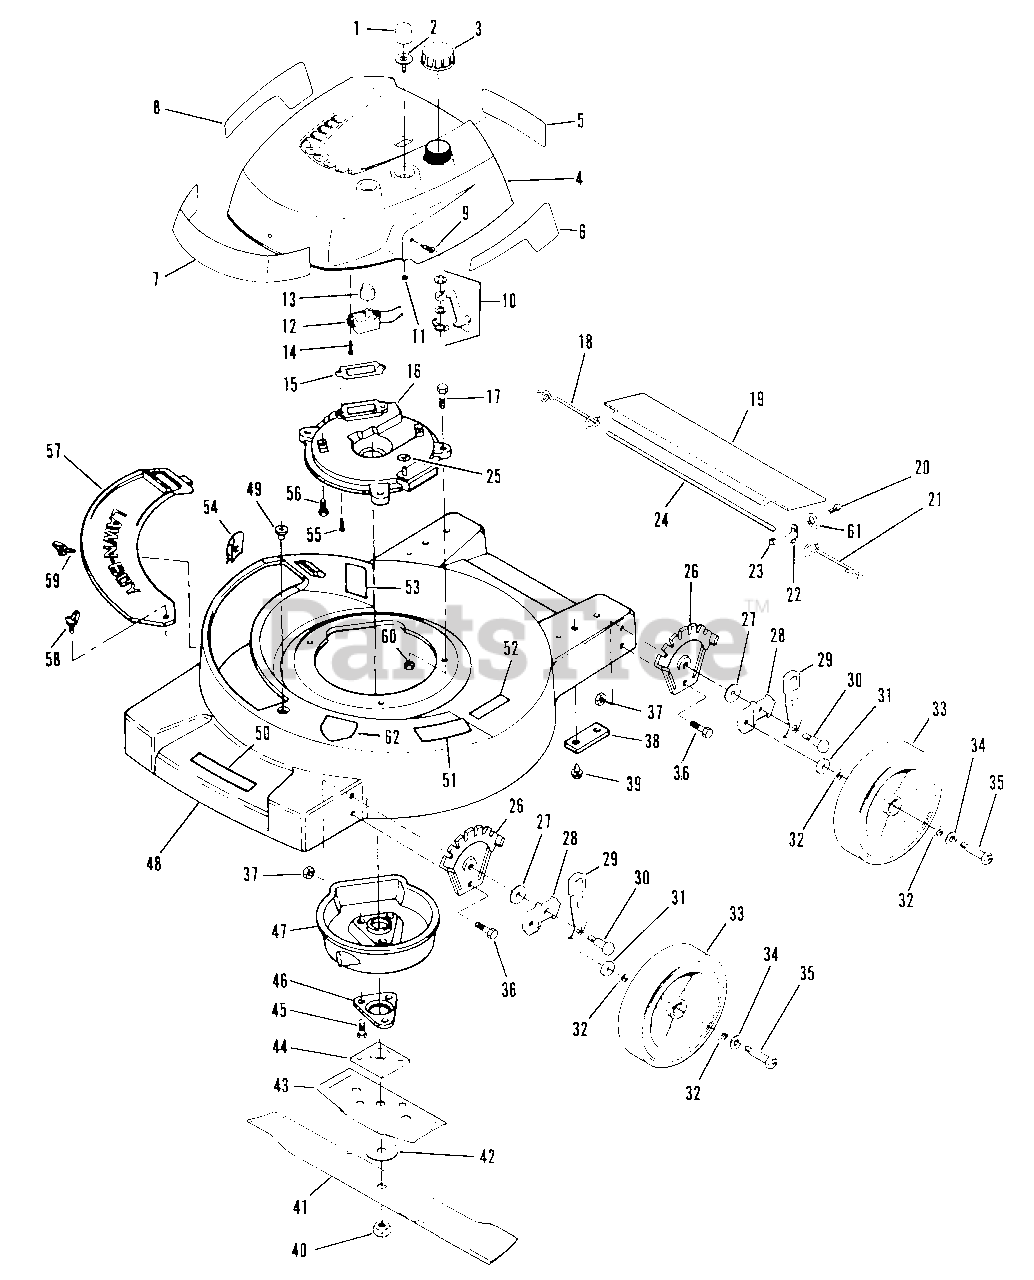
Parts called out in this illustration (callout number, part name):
1	Bulb-Primer
2	Base-Primer
3	Fuel Cap
4	Shroud-Engine
5	Decal-Instructions
6	Decal-L.H.
7	Decal-Lawn-Boy
8	Decal-R.H.
9	Screw-Shroud Mounting
10	Fuel Shut-Off Assembly
11	Nut
12	Switch-On-Off
13	Knob
14	Screw
15	Gasket-Exhaust
16	Plate-Muffler
17	Screw-Muffler Plate to Housing
18	Spring-R.H.
19	Shield-Trailing 21"
20	Screw
21	Spring-L.H.
22	Clamp
23	Nut
24	Rod-Trailing Shield 21"
25	Pushnut-Model Plate Mtg
26	Plate-Height Adjust
27	Washer
28	Bracket-Wheel Height Adjustment
29	Knob & Spring Assembly
30	Shoulder Bolt
31	Washer
32	Washer-Felt
33	Wheel
34	Washer
35	Bolt-Wheel
36	Screw-Plate Height Adjustment
37	Nut-Back-Up Plate & Adjustment Bracket
38	Spacer-Handle Bracket Screw
39	Screw-Handle Bracket to Housing
40	Nut-Blade
41	Blade-21"
42	Washer-Blade
43	Stiffener-Blade
44	Collar & Plate Assembly
45	Screw
46	Support-Crankshaft
47	Muffler Cover Assembly
48	Housing-21"
49	Grommet
50	Decal-Caution
51	Pad-Starting
52	Decal-Starting Pad
53	Decal-Discharge Area
54	Speed Nut-Cover Mounting
55	Screw-Muffler Plate to Block
56	Screw-Muffler Plate to Block
57	Cover Plate
58	Wing Screw
59	Thumb Screw-Cover Plate-Side
60	Nut-Muffler Plate to Housing
61	Washer
62	Decal-Blade contact Warning
